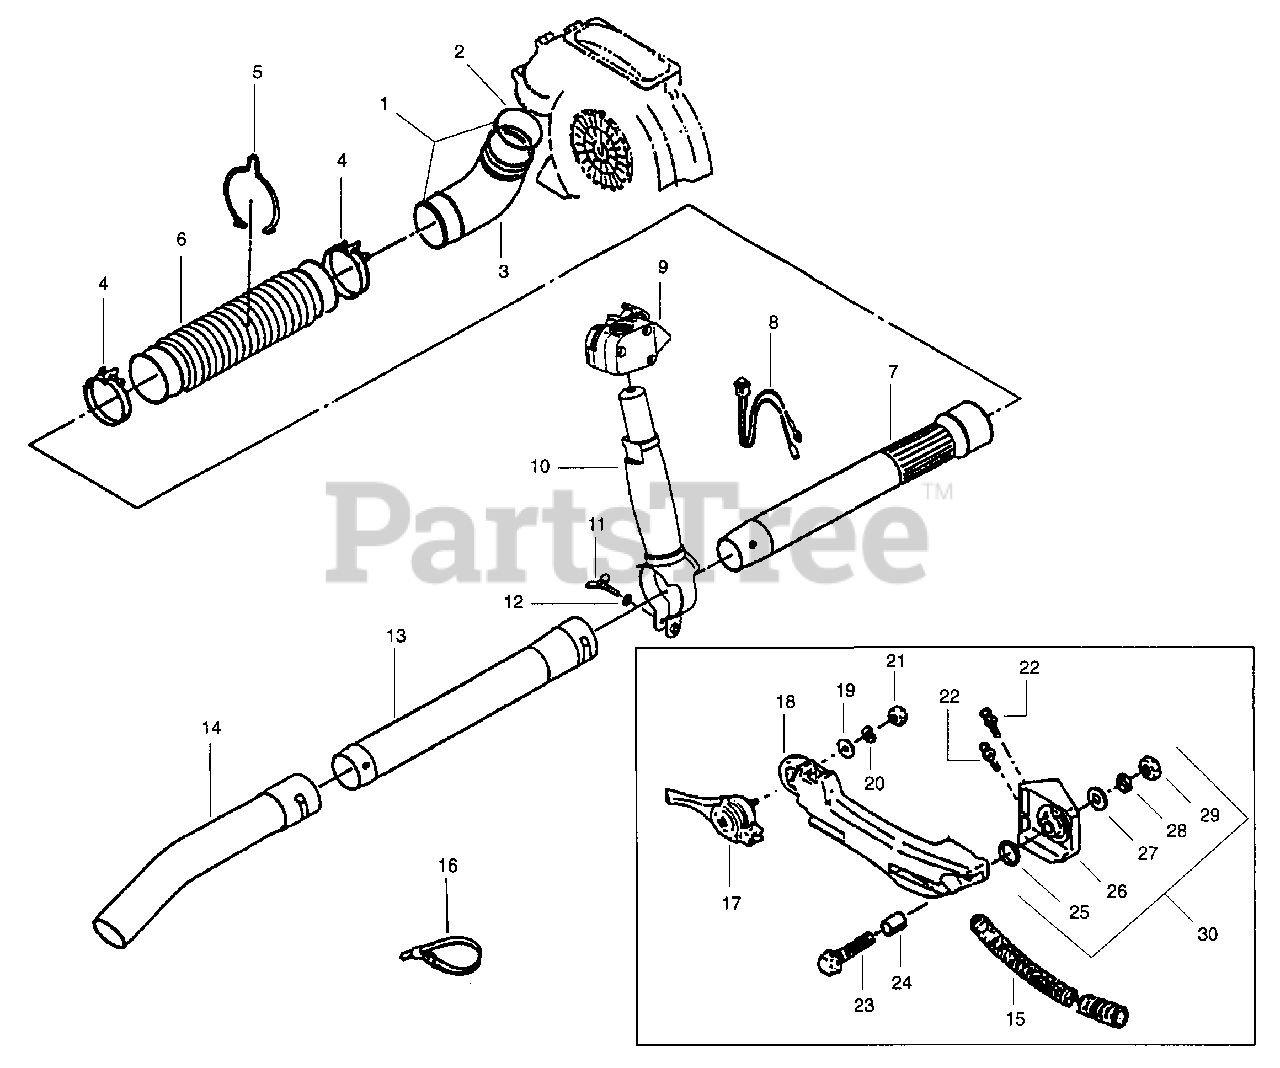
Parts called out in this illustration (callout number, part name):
1	Elbow Pipe Ass'y.
2	O-Ring
3	Elbow Pipe
4	Hose Band
5	Wire Clamp
6	Flexible Pipe
7	Base Pipe
8	Stop Switch
9	Throttle Lever Ass'y. - Type 2
10	Lever Ass'y.
11	Wire Bolt
13	Middle Pipe
14	Bend Pipe
15	Tube
16	Wire Band
17	Throttle Lever
20	Lockwasher
28	Lockwasher
30	Throttle Lever Ass'y. - Type 1
